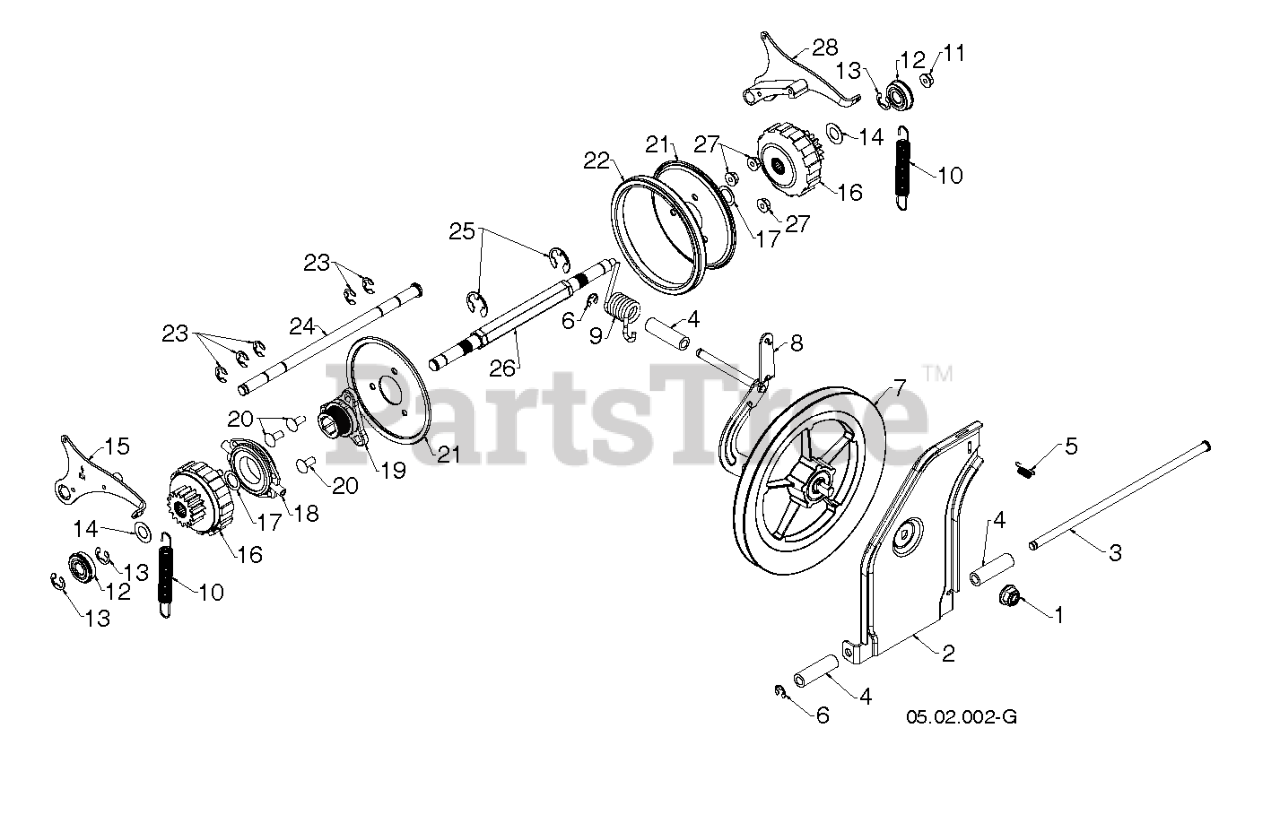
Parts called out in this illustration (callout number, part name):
1	NUT 1/2-13 HEX FLANGE NYLOK CL
2	PLATE.SWING.FRICTION PULLEY.47
3	ROD ROD,PIVOT, SWING PLATE ROD
4	RETAINER RING E-RING CLEAR ZI
5	SPRING LATCH
6	RETAINER RING E-RING CLEAR ZI
7	PULLEY.FRICTION.DISC.COMBO
8	BRACKET YOKE WELDMENT_MS 479
9	SPRING TORSION DRIVE
10	SPRING EXTENSION PS
11	NUT.HEX.FLANGE.LOCK.5/16-18
12	BEARING 9/16 ID. SNR
13	RING.RETAINING.1622-2RSNR.CLER
14	WASHER FLAT.637IDX1.00ODX21GA
15	PAWL.ASM.RH.SNOW
16	GEAR.ASM.PLANETARY
17	WASHER FLAT.59IDX1.065ODX25GA
18	TRUNNION BEARING ASSY
19	HUB.ASM.RUBBER WHEEL.SNO
20	RHSNB 5/16-18 X 3/4
21	PLATE.RUBBER.WHEEL.BLACK
22	RING RUBBER
23	CLIP E-RING_.500 SHAFT
24	ROD ROD, PAWL ROD
26	SHAFT SHAFT, PWR STR SHAFT
27	NUT.LOCK.5/16-18
28	PAWL.ASM.LH.SNOW
